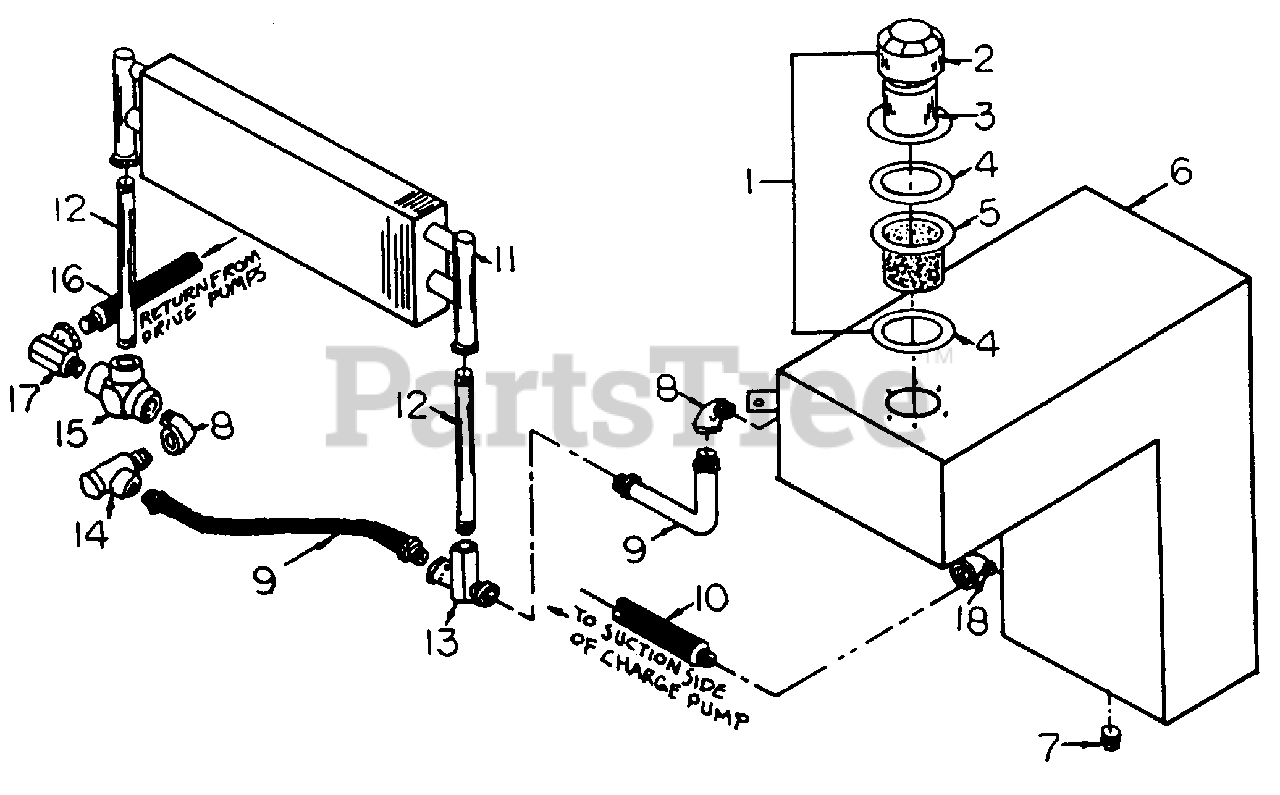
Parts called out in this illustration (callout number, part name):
1	Hydraulic Fill Cap Assembly
5	Strainer
6	Oil Reservoir
7	Pipe Plug, 1/2"
8	Male Pipe, 9ø Female Pipe Adpt.
9	Easy Couple Hose, 1/2" I.D. x 10 5/8" Long
10	Easy Couple Hose, 3/4" ID x 21" Lg.
11	Oil Cooler
12	Pipe Nipple, 1/2" x 10"
13	Female Pipe, Female Pipe Swivel Tee
14	Relief Valve
15	Female Pipe Tee
16	Easy Couple Hose, 1/2" ID x 29" Long
17	Male Pipe, 90ø Male Tube Adapter 4 Cylinder
18	Male Pipe, 45ø Female Pipe Adpt.
